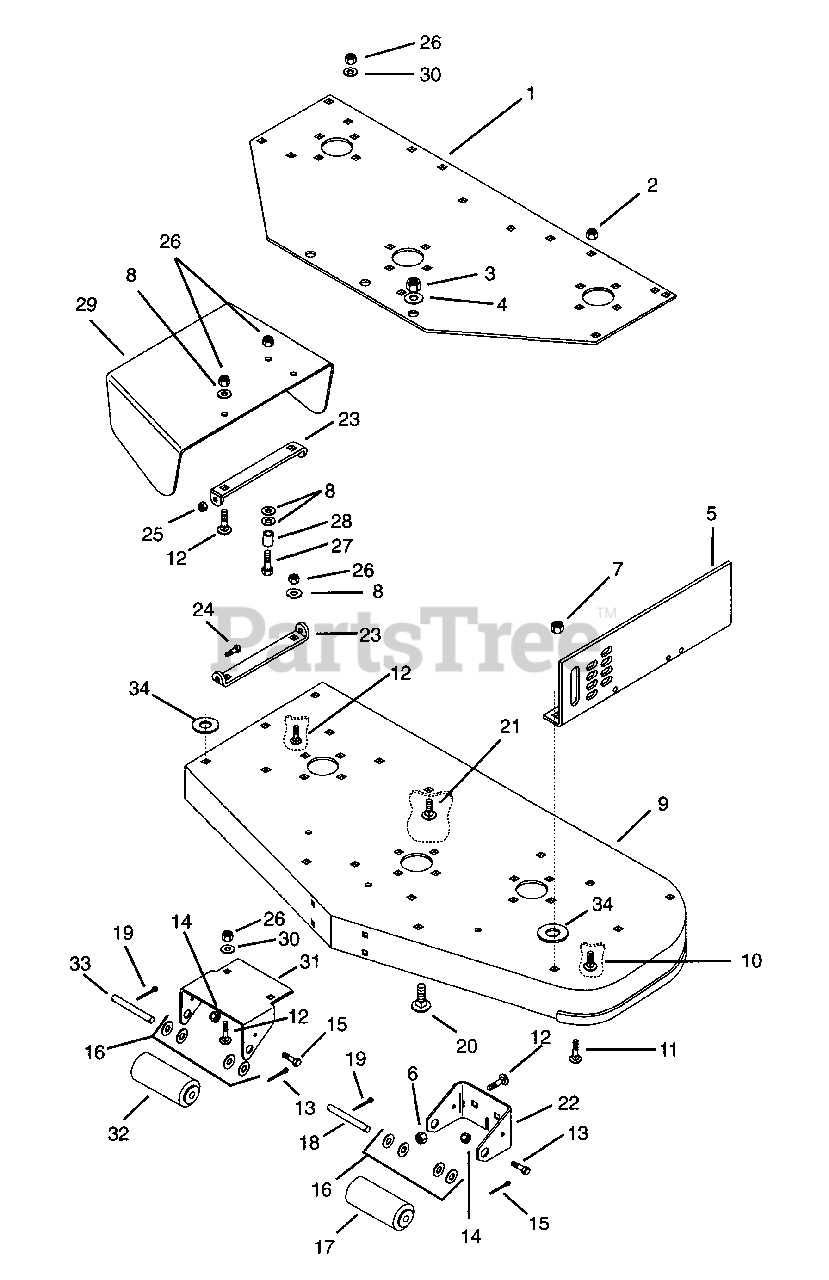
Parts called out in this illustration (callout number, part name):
1	Plate, Support
2	Nut-Locking-Nylon .312-18 Grade 2
3	Nut-Locking-Nylon .50-13 Grade 5
4	Washer-Flat-Steel .531 x 1.250 x .100
5	Bracket, Mower Side Support Left Hand
5	Bracket, Mower Side Support Right Hand
6	Nut-Locking-Nylon .375-16 Grade 2
7	Nut-Locking-Nylon .312-18 Grade 2
8	Washer-Flat-Steel .406 x .812 x .065
9	Weldment, 50" Mower Fabricated
10	Bolt-Round Head Square Neck .31-18 x .62
11	Bolt-Round Head Square Neck .31-18 x 1.0
12	Bolt-Round Head Square Neck .38-16 x 1.0
13	Bolt-Hex .25-20 x .75 Grade 5
14	Nut-Locking-Nylon .250-20 Grade 2
15	Pin-Cotter .250 x 2.00
16	Washer-Flat-Steel .656 x 1.312 x .095
17	Roller, Gage
18	Rod
19	Pin-Cotter .25 x 1.00
20	Bolt-Round Head Square Neck .50-13 x 1.00
21	Bolt-Round Head Square Neck .375-16 x .75 Grade 1
22	Bracket, Roller
23	Bracket, Chute
24	Bolt-Hex .25-20 x .875
25	Nut-Locking-Nylon .250-20 Grade 2
26	Nut-Locking-Nylon .375-16 Grade 2
27	Bolt-Hex .38-16 x 1.50 Grade 5
28	Bushing-Sleeve .407 x .625 x .750
29	Shield, Safety External 50" Mower
30	Washer-Flat-Steel .406 x .812 x .065
31	Bracket, Roller Right Hand
32	Roller, Gage
33	Shaft, Center Roller
34	Bushing-Spacer
